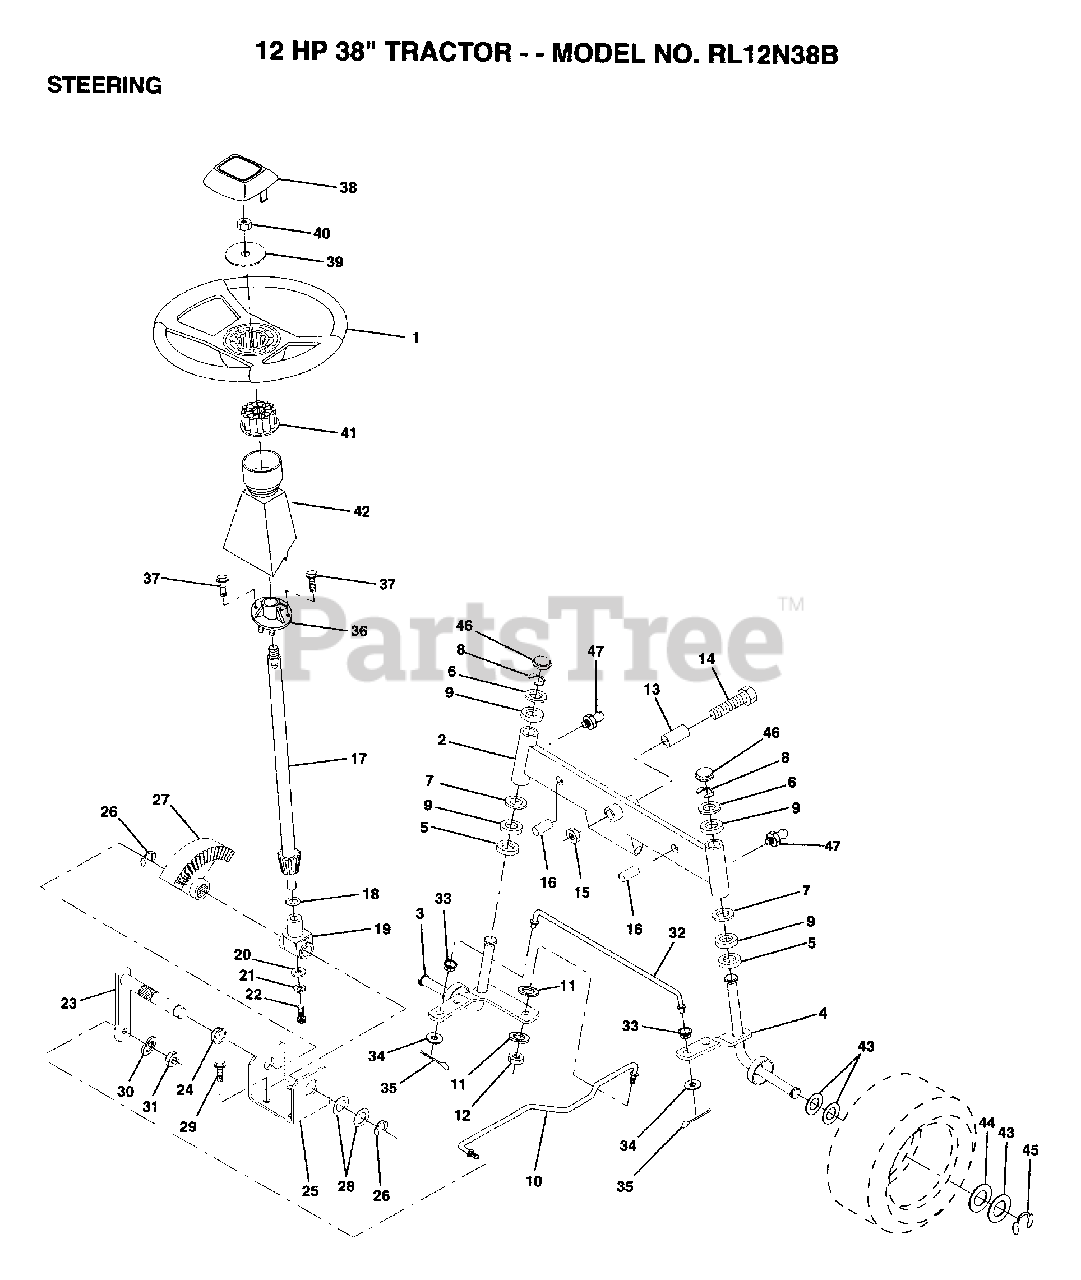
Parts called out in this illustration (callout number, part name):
3	SPINDLE LH
4	SPINDLE RH
5	WASHER .T
6	WASHER
7	WASHER
8	RING
9	COL. SRTG. BEAR.
11	LOCKWASHER
13	BEARING
14	BOLT HEX 5/8-11
15	"NUT-LOC,FLANGE LT"
16	AXLE PIN
17	SHAFT ASM
18	THRUST WASHER
19	SUPPORT.SHAFT
21	LOCKWASHER
22	"SCREW,SPECIAL"
24	NYLINER T
25	"BRKT,STEERING"
26	RING
27	GEAR SECTOR
28	WASHER .T
29	SCREW
30	LOCKWASHER
32	TIE ROD
33	BUSHING.DRAGLINK
34	WASHER
35	COTTER PIN
38	ST WHL INSERT CAP
39	WASHER T
40	GRIPCO NUT
41	ADAPTER-WHEEL LT
42	"TUBE, STR SHAFT"
43	WASHER
44	WASHER
45	RING
46	CAP
47	ZERK M
